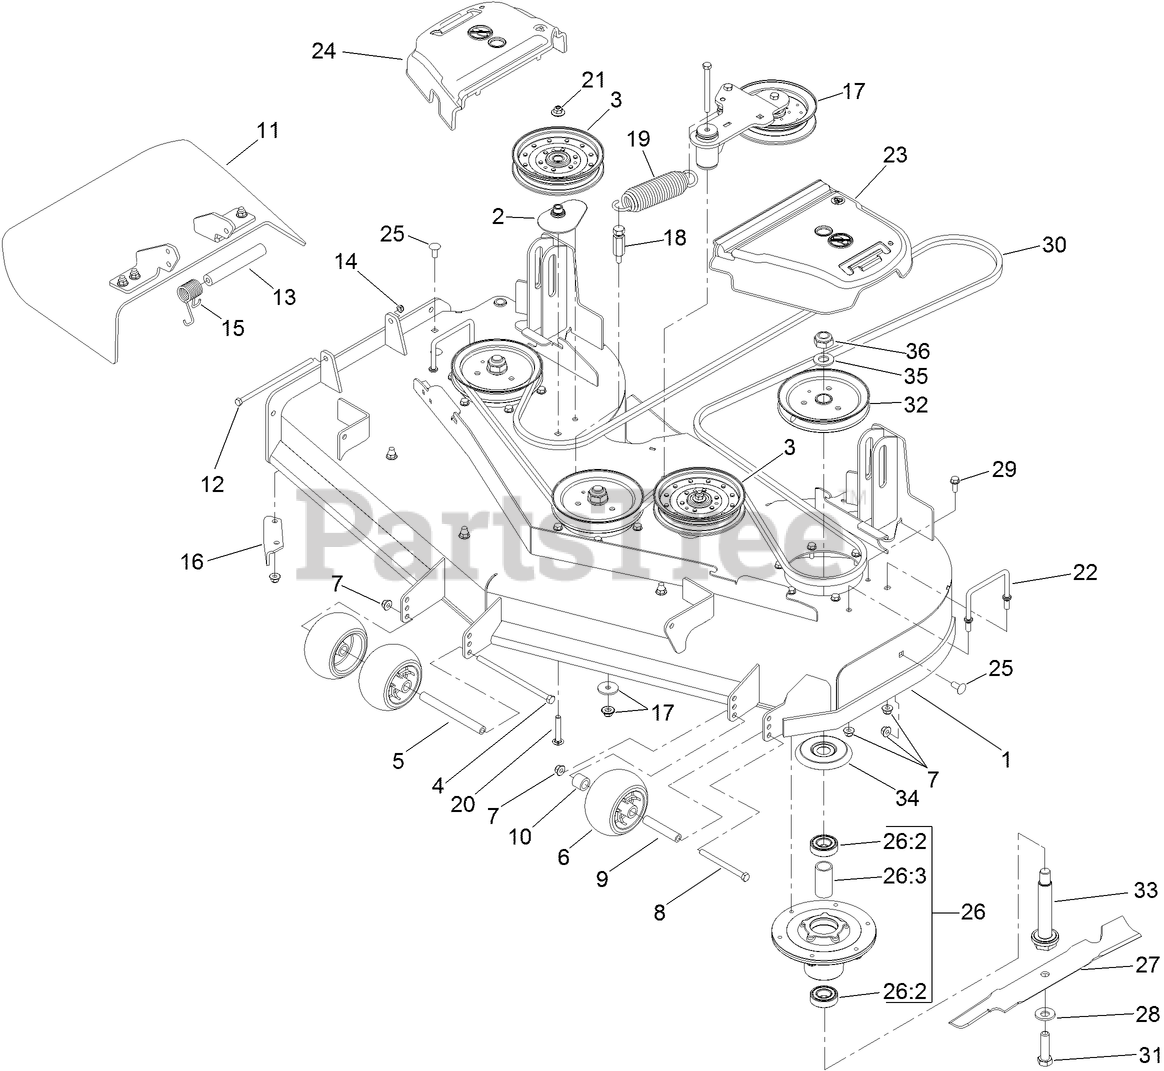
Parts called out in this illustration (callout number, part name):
1	DECK DECAL ASM
2	SPACER-PULLEY
3	PULLEY-IDLER, FLAT
4	SCREW-HH
5	SPACER-WHEEL
6	ROLLER-SCALP, ANTI
7	NUT-HF, NI
8	SCREW-HH
9	TUBE-SPANNER
10	TUBE-SPACER
11	DEFLECTOR ASM
12	SCREW-HH
13	SPACER
14	NUT-LOCK, NI
15	SPRING-TORSION
16	BAFFLE-DISCHARGE
17	IDLER ARM ASM
18	ANCHOR-SPRING, TALL
19	EXTENSION-SPRING
20	BOLT-CARR, SHORT NECK
21	NUT-FLANGE, NI
22	WIREFORM-COVER
23	COVER-BELT, LH
24	COVER-BELT, RH
25	SCREW-CARR
26	SPINDLE ASM
26:2	BEARING-BALL
26:3	SPACER-BEARING
27	BLADE-HI FLOW, 18 IN
28	WASHER-BELLEVILLE
29	SCREW-TAPTITE
30	BELT-V
31	SCREW-BLADE
32	PULLEY
33	SPINDLE-SHAFT
34	SHIELD-BEARING
35	WASHER
36	NUT-LOCK, NI
